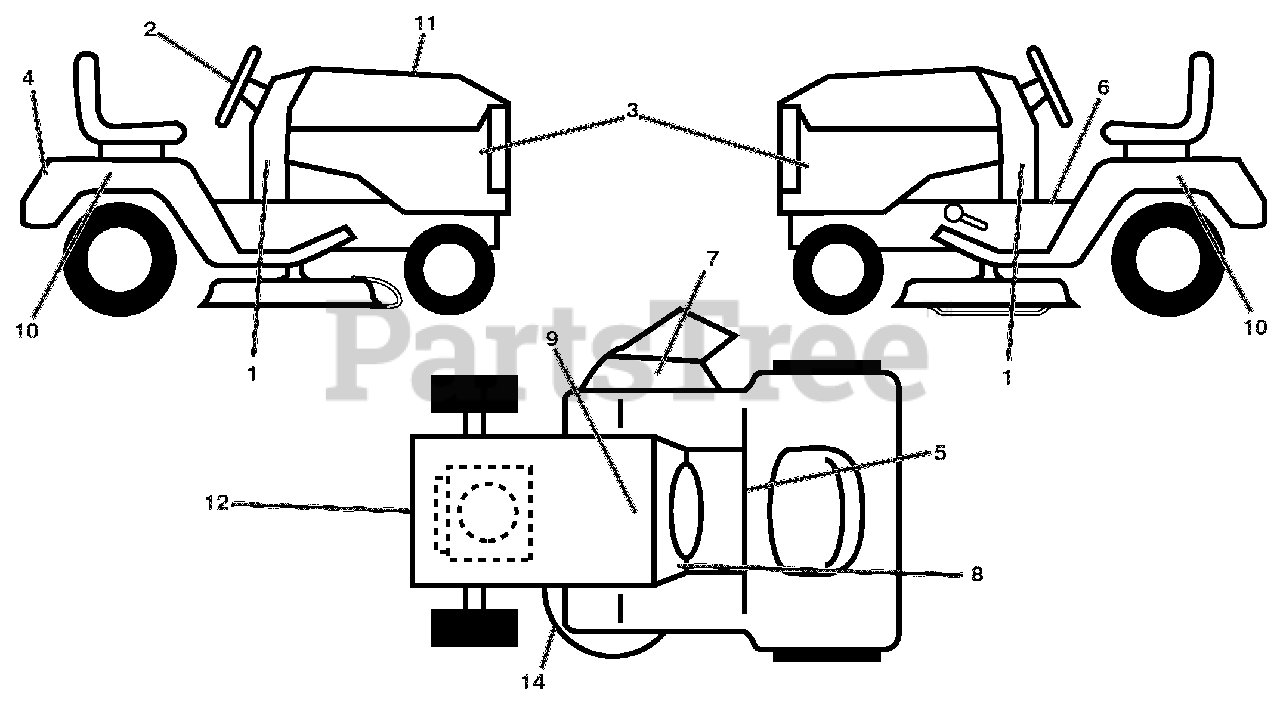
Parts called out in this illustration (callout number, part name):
1	DECAL.DASH
2	DECAL.WHEEL.STEER.ARIENS
3	DECAL.SDPNL.PWRDBY B&S.ARIENS
4	DECAL.FENDER.REAR.ARIENS
5	DECAL.FENDER
6	DECAL.WARNING.START
7	DECAL DECK/DEFLECT. WARNING
8	DECAL.SNOWFLAKE
9	DECAL.BAT.DAN/POI P/L SYM.WPN
10	DECAL.FENDER.SIDE.HYDRO
11	DECAL REPLACEMENT
12	DECAL.ENGINE
14	DECAL.V-BELT.SCH.
